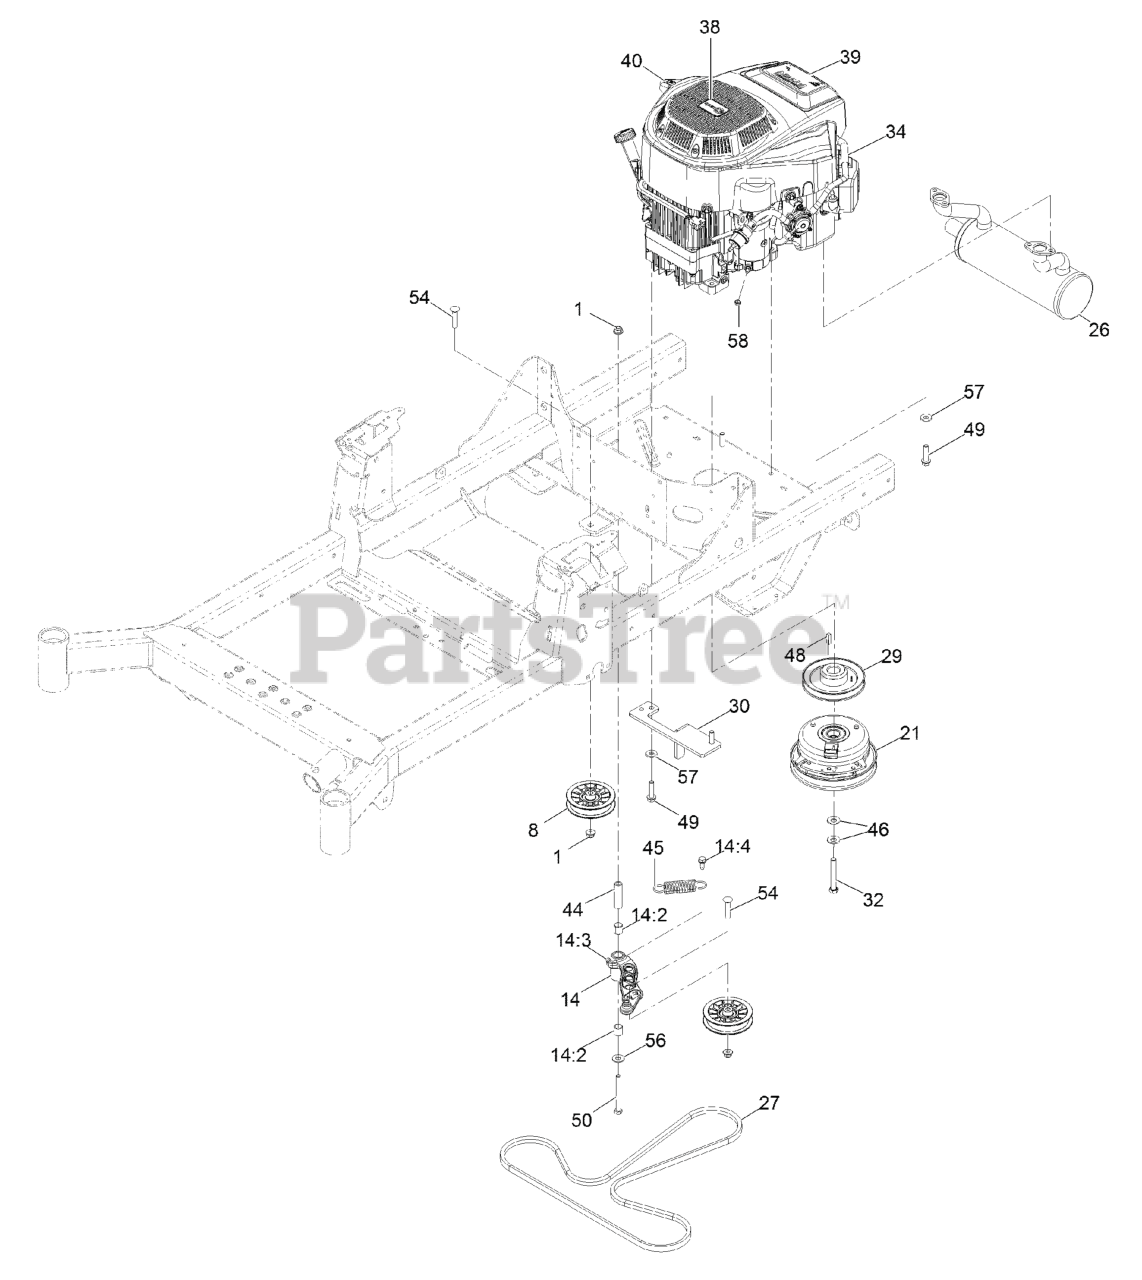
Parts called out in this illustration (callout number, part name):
1	NUT-HF, NI
8	PULLEY-FLAT IDLER
14	IDLER ARM ASM
14:2	SLEEVE-BEARING
14:3	FITTING-GREASE, 90 DEG
14:4	SCREW-THD ROLL, HWH
21	CLUTCH 1.00
26	MUFFLER
27	BELT-V
29	SHEAVE-ENGINE
30	ANCHOR-CLUTCH
32	SCREW-HH W/LOCTITE
34	ENGINE-2P77F
39	DECAL-708CC V-TWIN ENGINE
40	DECAL-DRAIN, OIL
44	BUSHING-PIVOT, IDLER
45	SPRING-EXTENSION
46	WASHER-SPRING
49	SCREW-HWH
50	SCREW-HH
54	SCREW-CARR
56	WASHER-FLAT
57	WASHER-BELLEVILLE
